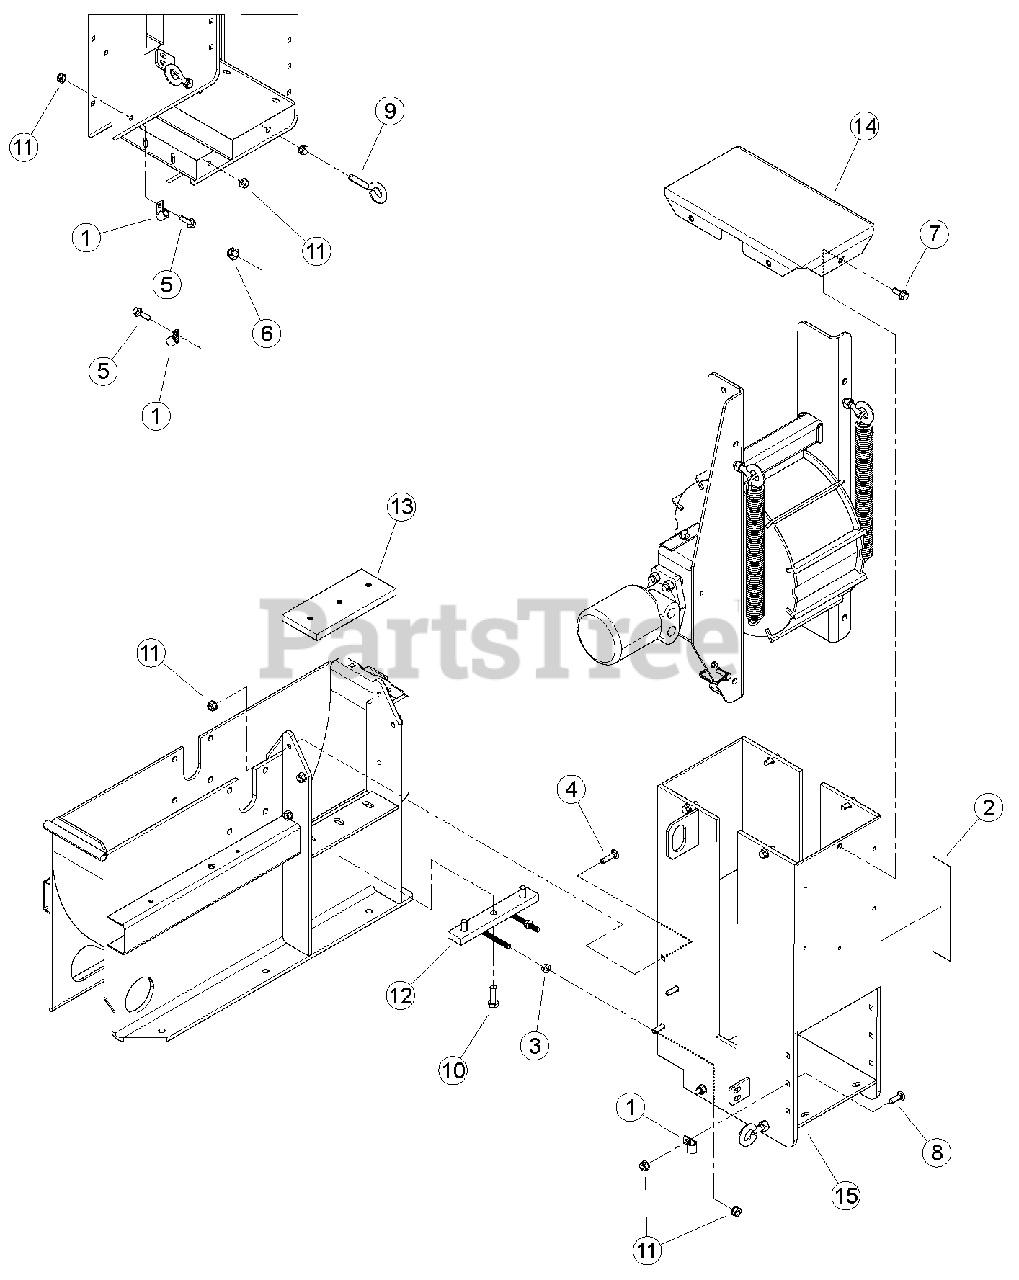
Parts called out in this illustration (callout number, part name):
1	CLAMP, 9/16 COATED
2	DECAL, CHIPPER ENGAGEMENT
3	NUT, 3/8" SERRATED FLANGE NC ZP
4	BOLT, 3/8 X 1-1/2" GR5 CRG NC ZP
5	BOLT, 3/8 X 1-1/4 FLANGE NC
6	NUT, 1/2-13 NYLOCK FLANGE
7	BOLT, 3/8 X 1 FLANGE NC
8	BOLT, 3/8 X 1-1/4"GR5 CRG NC ZP
9	EYEBOLT, 1/2 X 2" ZP
10	BOLT, 1/2 X 1-1/2 GR8 NC ZP HEX HD
11	NUT, 3/8-16 NYLOCK FLANGE
12	WELDMENT, BLOCK ADJUSTOR
13	PLATE, CHIPPER BOTTOM
14	WELDMENT, TOP ROLLER COVER
15	WELDMENT, ROLLER SUPPORT
